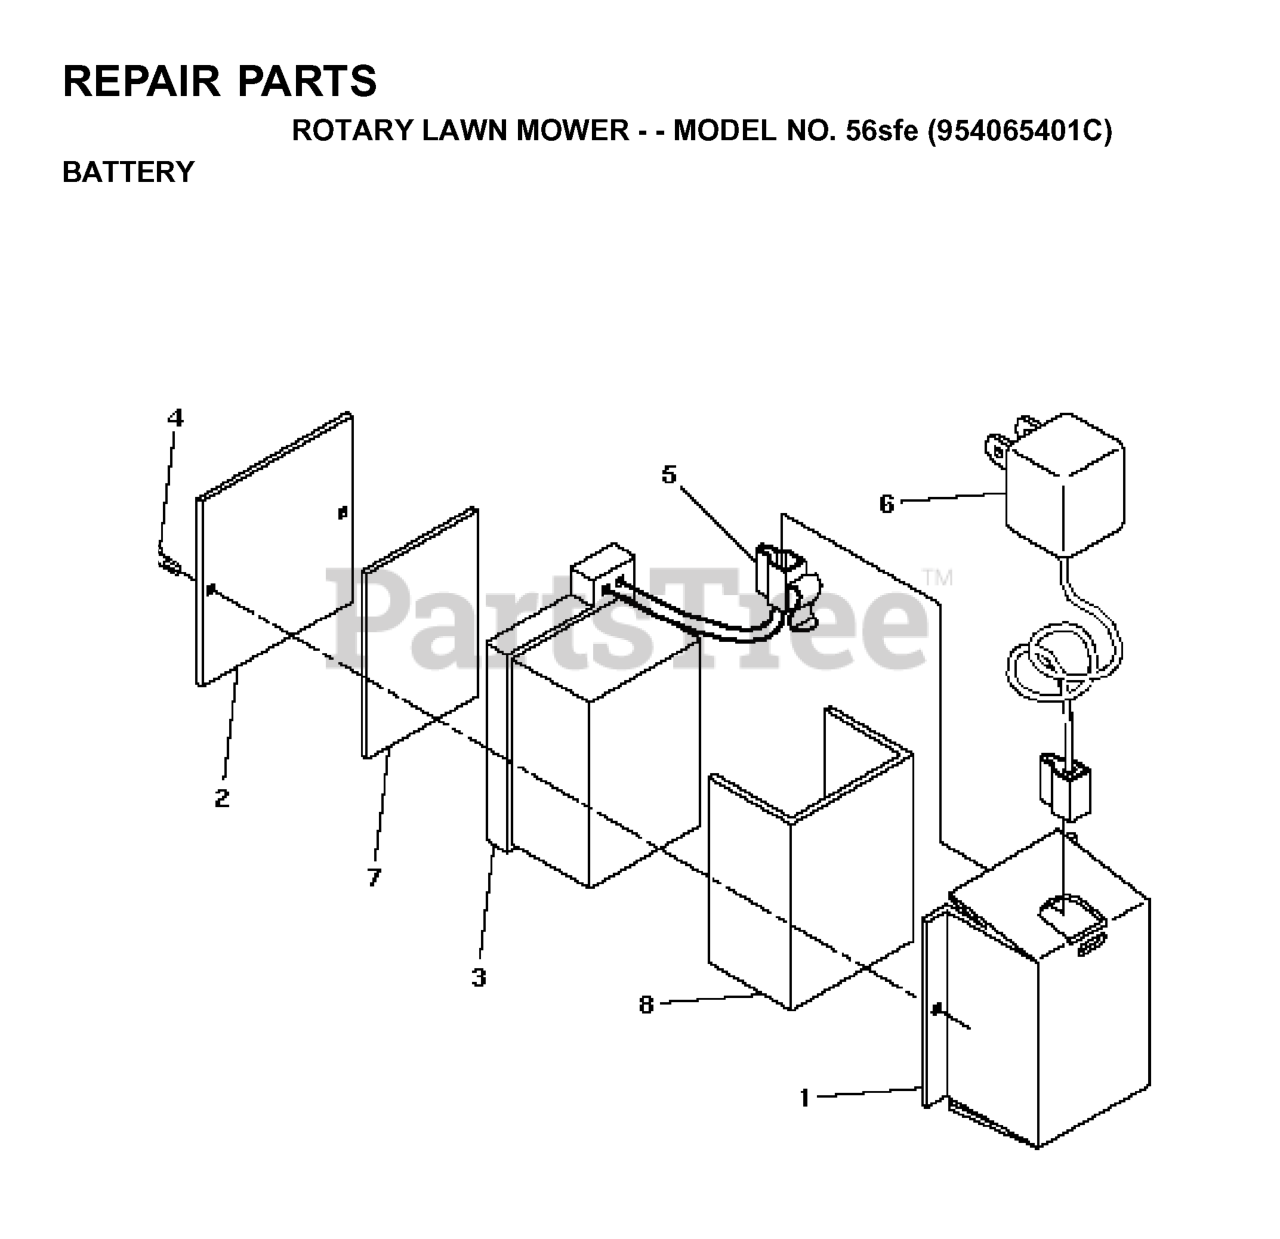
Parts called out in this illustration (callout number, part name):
3	KIT BATTERY REPL
4	TAPPING SCREW
5	CONNECTOR PM
6	KIT.CHARGER.BATTERY.
7	BATTERY PAD PM
8	BATTERY WRAP
